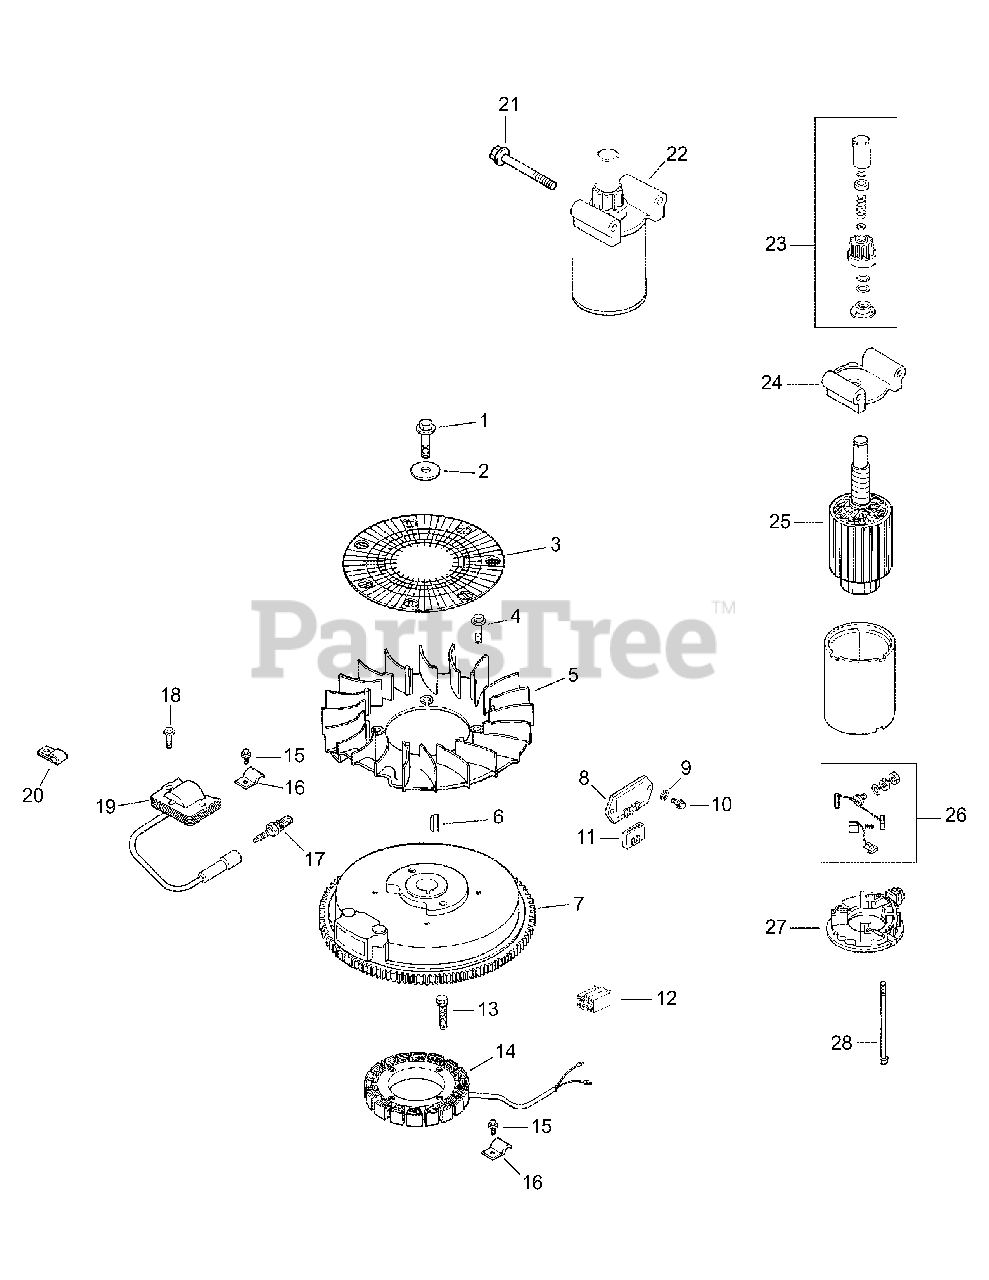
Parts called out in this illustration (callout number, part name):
1	Screw, Hex. Flange M10 x 1.5 x 46
2	Washer, Plain 3/8"
3	Screen, Grass
4	Bolt, Shoulder M6 x 1.0 x 16
7	Flywheel
8	Rectifier-regulator
9	Washer, Lock 1/4
10	Screw, Hex. Flange M6 x 1.0 x 16
11	Connector, Rectifier-regulator (3 Contact)
12	Connector (4 Contact)
13	Screw, Hex. Cap M5 x 0.8 x 25
14	Kit, Stator (Includes Terminal 25 452 01-S)
15	Screw, Hex. Flange M5 x 0.8 x 10
17	Spark Plug
18	Screw, Hex. Flange M5 x 0.8 x 20
19	Module, Ignition
21	Screw, Hex. Flange M8 x 1.25 x 70
22	Starter Assembly (Includes 3-8)
24	Cap, Drive End
25	Armature
26	Brush Assembly
27	Commutator, End Cap
